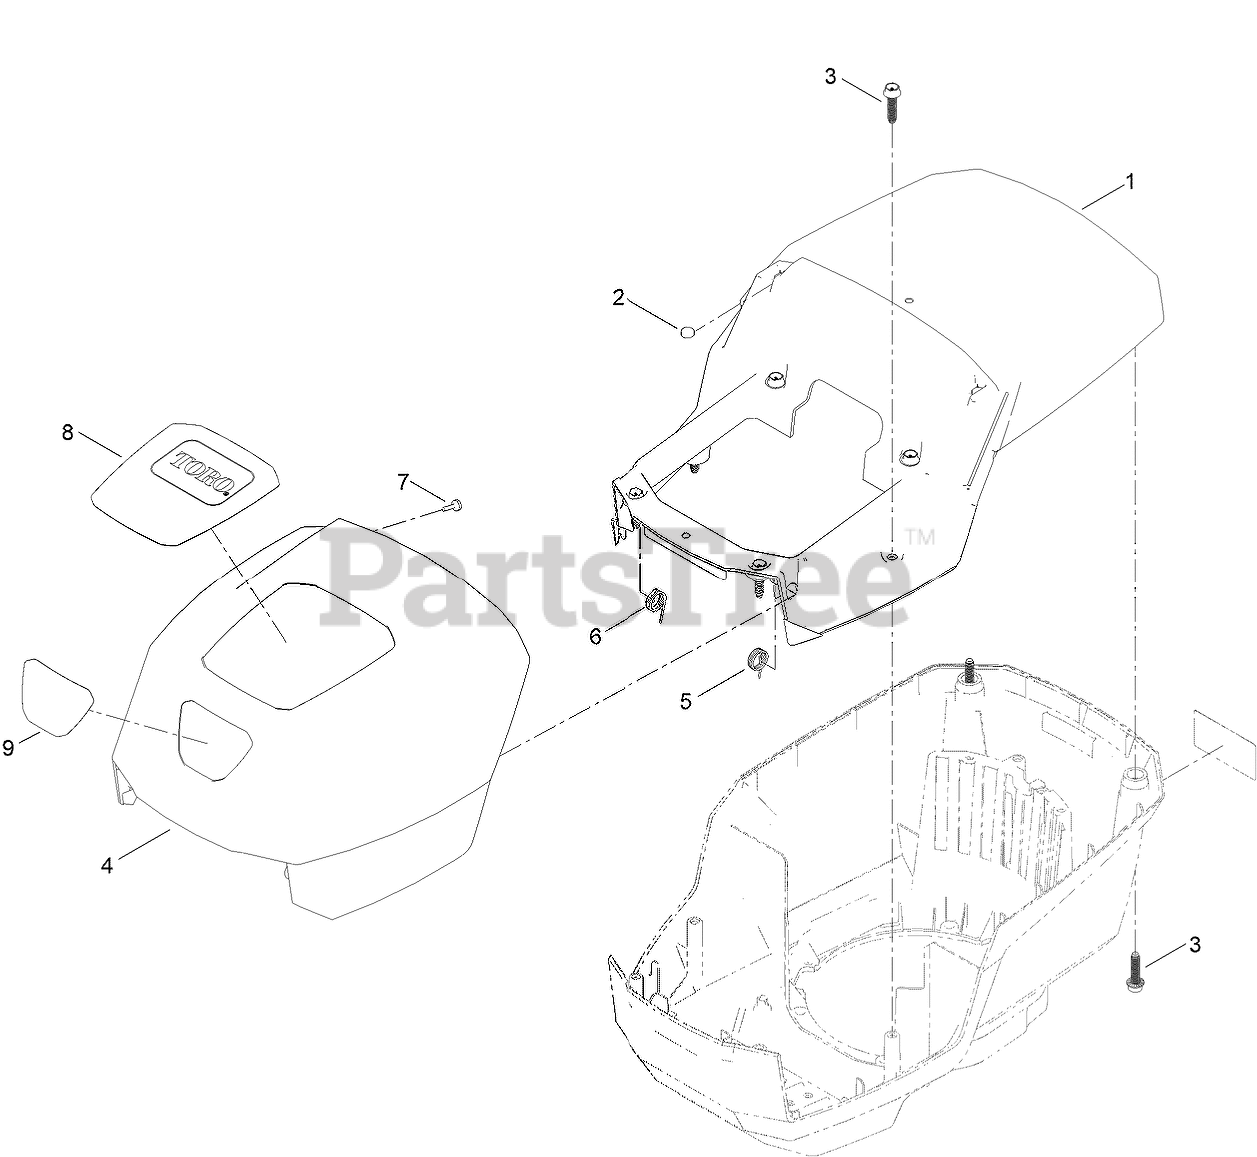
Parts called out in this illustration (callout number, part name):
1	SHROUD-UPPER
2	MAGNET
3	SCREW-FLANGE, PLASTIC
5	SPRING-LH
6	SPRING-RH
7	SCREW-PPH
8	DECAL-HOOD, TOP
9	DECAL-HOOD, FRONT
